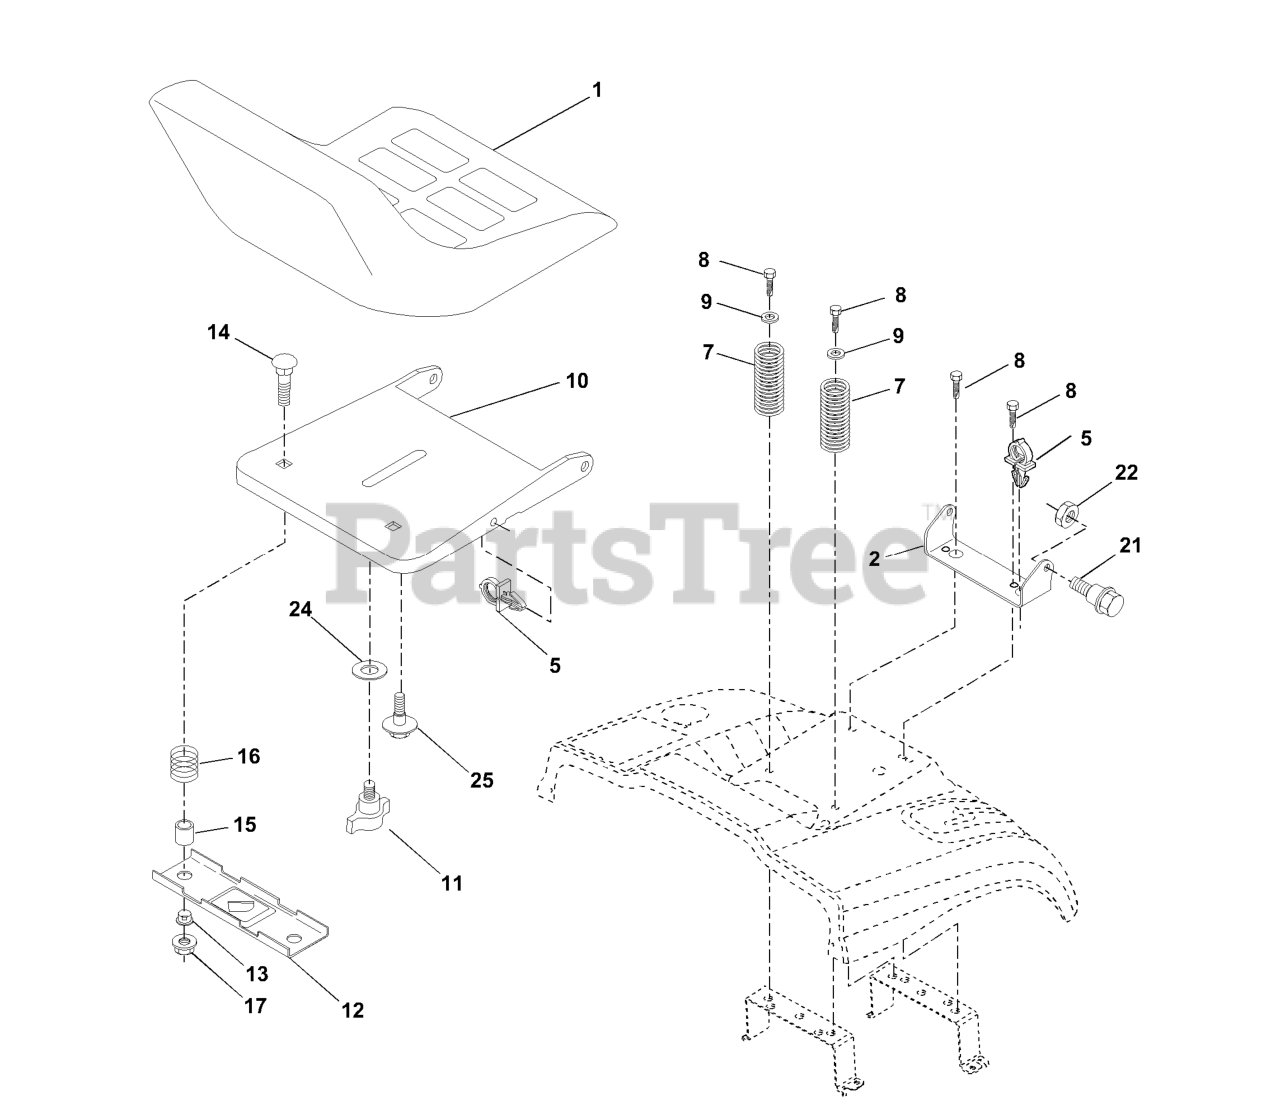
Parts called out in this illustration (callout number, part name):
1	SEAT, GRAY
2	SEAT PIVOT BRKT
7	SPRING COMPRESSION
8	SCREW 3/8-16 X 1/2
9	WASHER 13/32 X 1 X 14 GA.
10	PAN, SEAT
11	KNOB.SEAT.ADJ.WINGNUT
12	BRKT SWITCH
14	BOLT
15	SPACER SPLIT 28X.96
17	NUT LOCK
21	BOLT
22	NUT
24	WASHER
25	BOLT
